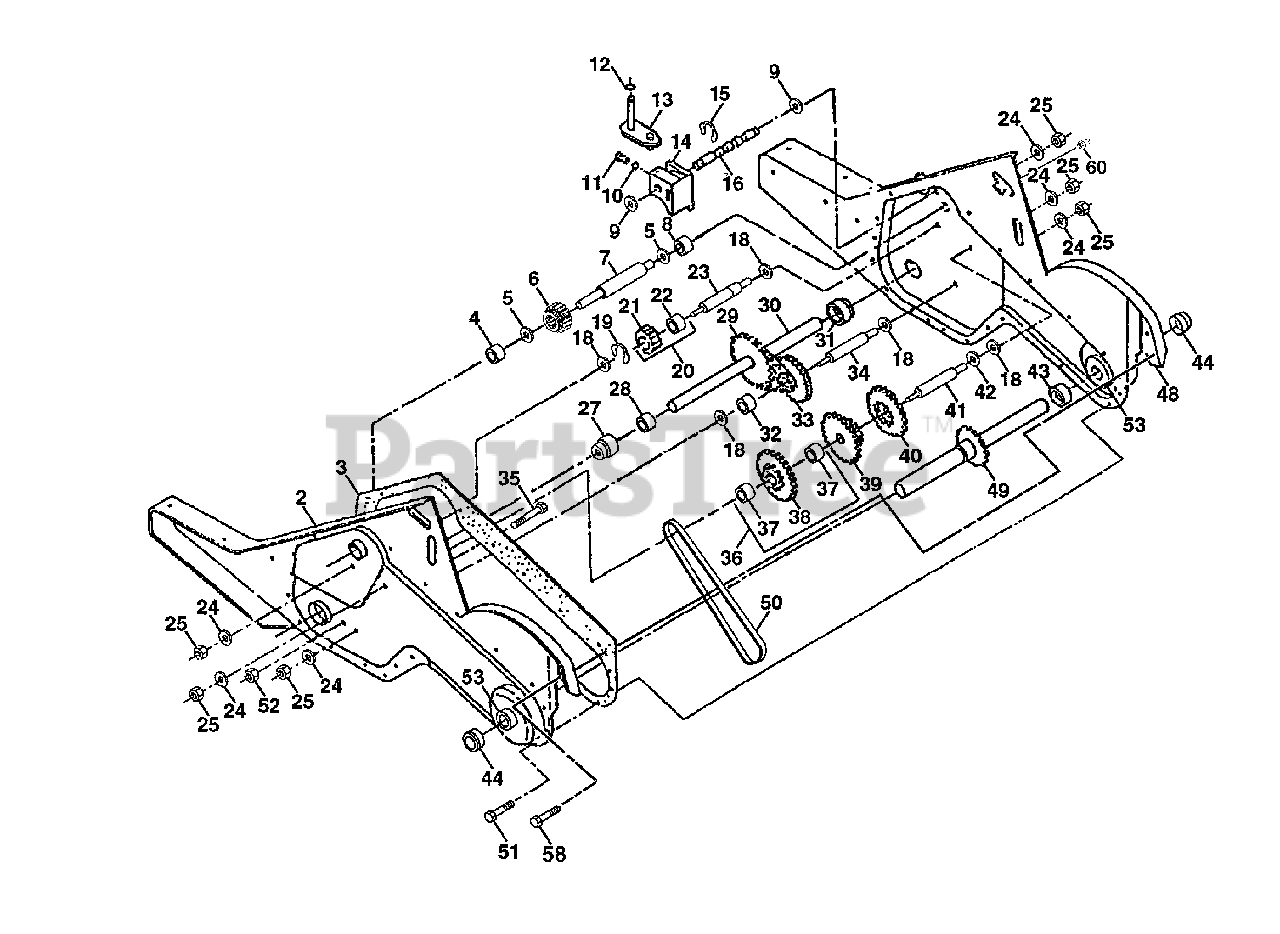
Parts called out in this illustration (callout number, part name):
1	Transmission Assembly
2	Gearcase, L.H. w/Bearing
3	Gasket, Gearcase
4	Bearing, Needle
5	Washer, Thrust 5/8 x 1.10 x 1/32
6	Pinion, Input
7	Shaft, Input
8	Bearing, Needle
9	Washer, Seal
10	Ball, Steel
11	Spring, Shift, Fork
12	O-Ring
13	Bracket, Shift
14	Fork, Shift
15	Ring, Klip
16	Shaft, Shift
18	Washer
19	Ring, Klip
20	Gear, Assembly, Reverse Idler
21	Gear, Reverse Idler
22	Bearing, Needle
23	Shaft, Reverse Idler
24	Washer, Lock 7/16
25	Nut, Hex 7/16-20
27	Bearing, Shaft, Ground Drive L.H.
28	Spacer 0.765 x 1.125 x 1.23
29	Chain #35-50 Pitch
30	Ground Shaft Assembly
31	Bearing, Shaft, Ground Drive R.H.
32	Spacer 0.70 x 1.00 x 1.150
33	Sprocket and Gear Assembly
34	Shaft, Reduction (2nd)
35	Screw, Whiz, Lock 5/16-18 x 3-1/2
36	Sprocket Assembly w/Bearing
37	Bearing, Needle
38	Sprocket, Tine
39	Gear, Cluster, Red 1st & 2nd
40	Gear, Reverse
41	Shaft, Reduction (1st)
42	Washer, Thrust
43	Spacer 1.01 x 1.75 x 0.760
44	Seal, Asm. Oil
48	Gearcase, R.H. w/Bearing
49	Shaft, Tine
50	Chain, Roller #50-50 Pitch
51	Screw 1/4-20 x 1/2
52	Nut, Hex 5/16-18
53	Kit, Bearing, Tine Shaft
58	Screw 1/4-20 x 3/4
60	Fitting Grease
60	Grease, Plastilube #1
